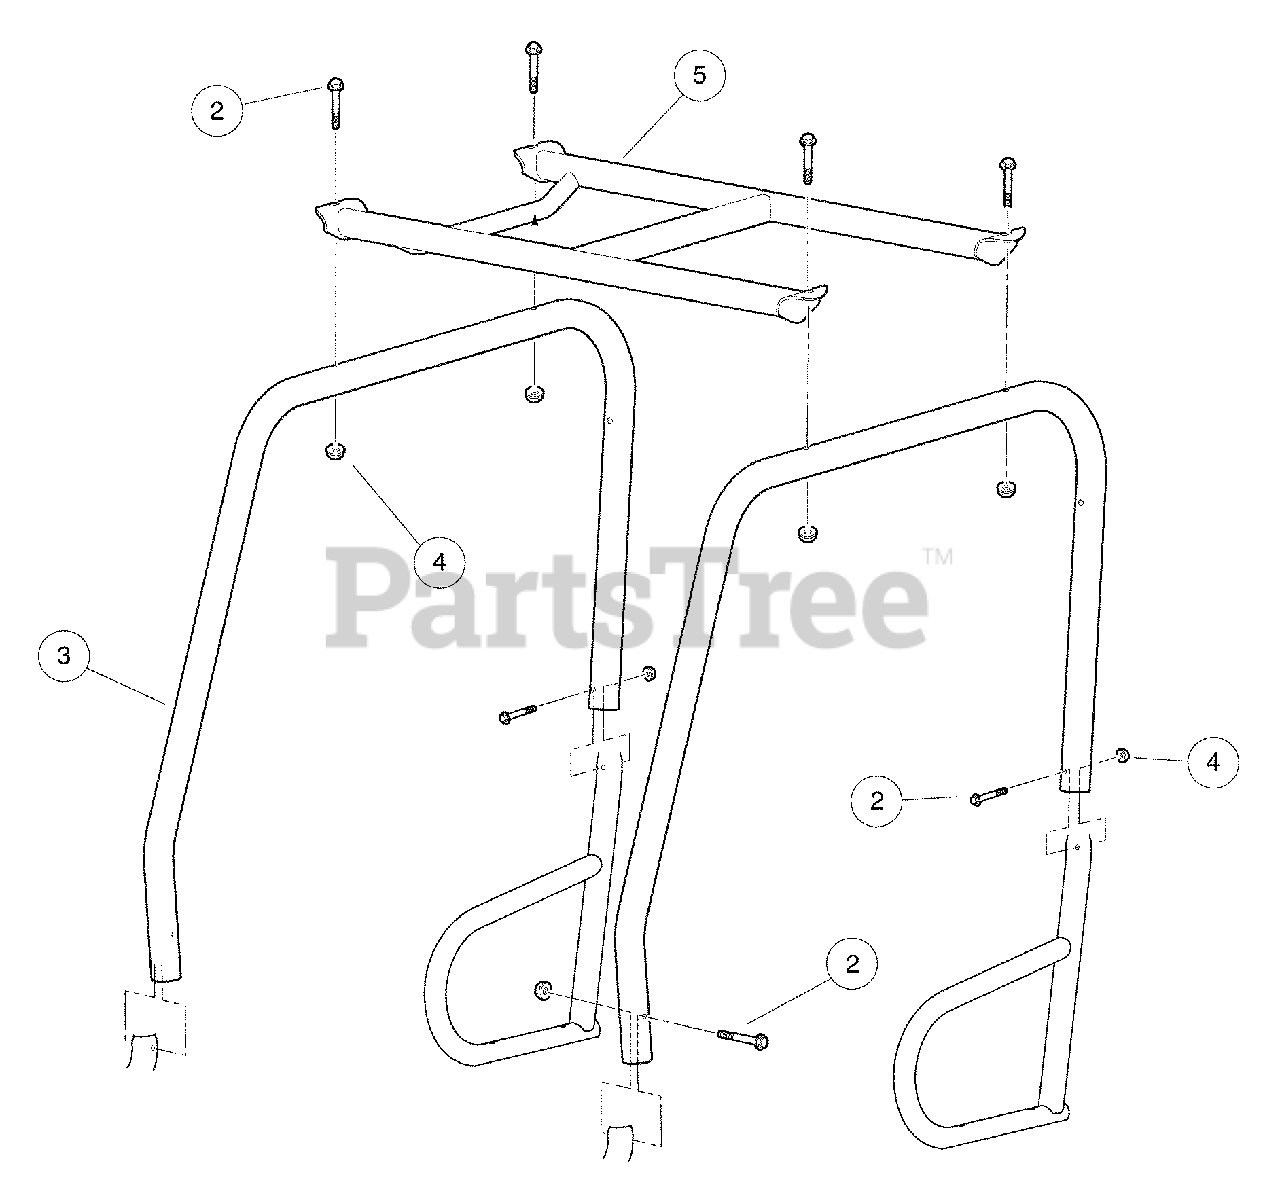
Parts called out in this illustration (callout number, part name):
1	Kit, ROPS, Domestic
2	Bolt, Flanged, M10 X 1.5 X 65.
3	Tube, Side Support Short, ROPS
4	Nut, Flanged, M10 x 1.5, Black
5	Asm, Top, ROPS
